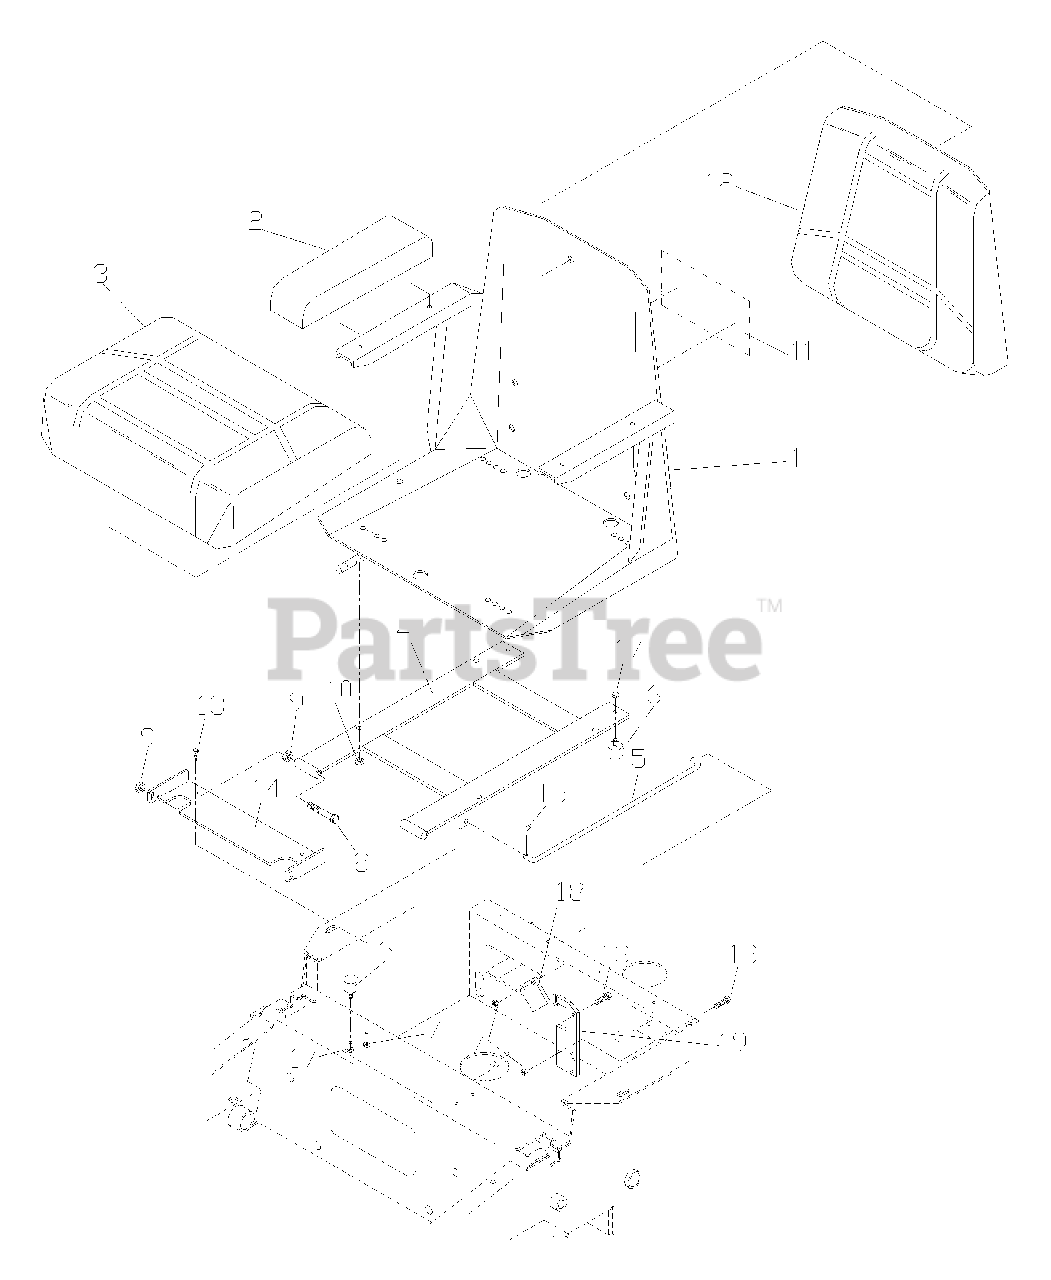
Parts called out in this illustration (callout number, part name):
1	SEAT COMPLETE
2	ARM REST CUSHIONS (1 PAIR)
3	SEAT CUSHION W/SWITCH
4	SEAT MOUNT
7	NUT 1/4 LOCK
8	HCS 3/8 X 3.0
9	NUT 3/8 LOCK
10	NUT 5/16 NYLOC
11	DECAL, CROWN
12	BACK CUSHION
13	HCS 1/4 X 3/4
14	SEAT BRACKET W/DECAL
15	COTTER PIN
17	NUT 1/4 NYLOC
18	SEAT LATCH
19	SEAT LATCH MOUNT
